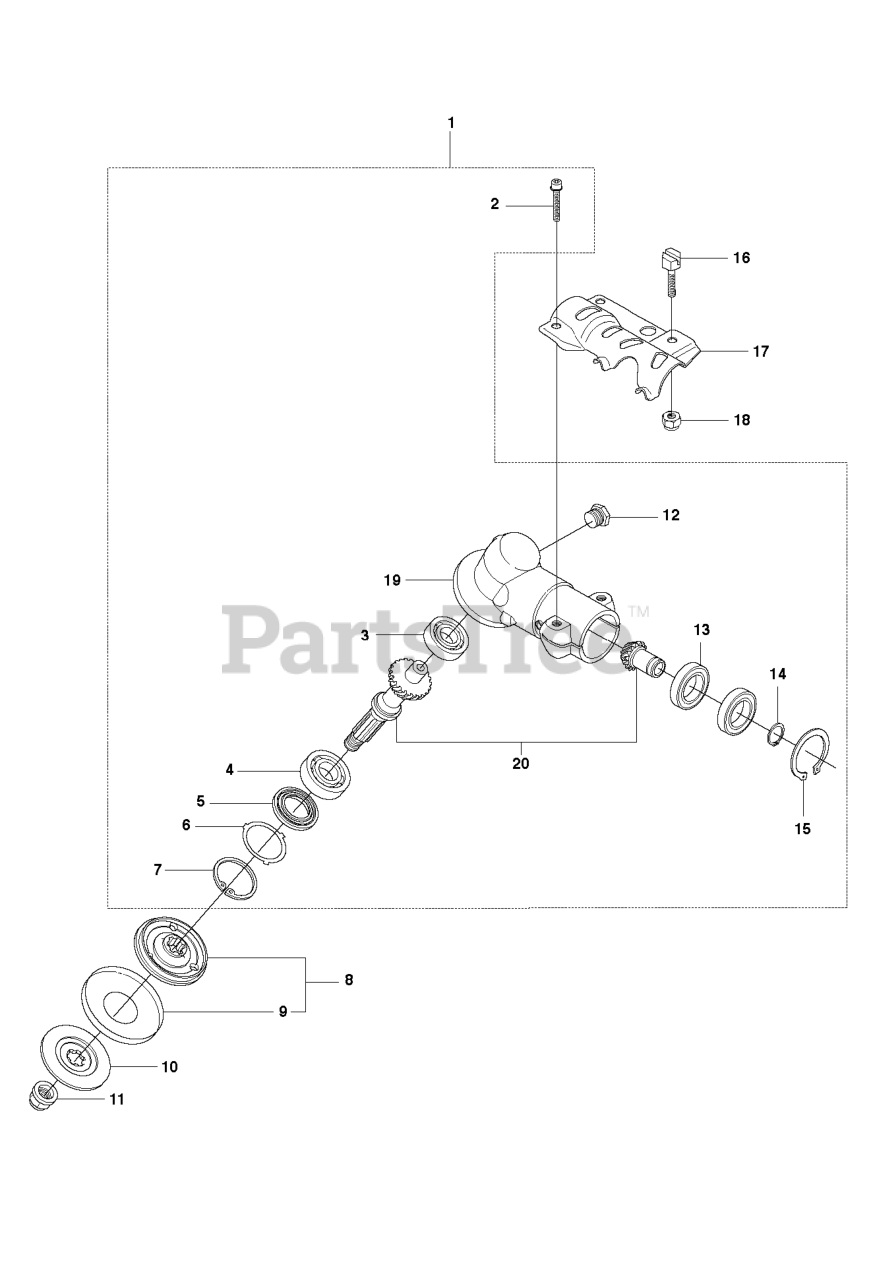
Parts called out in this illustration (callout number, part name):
1	GEAR ASSY
3	BALL BEARING
4	BALL BEARING
7	RETAINING RING SGH 35
8	RP CARRIER
9	RP TUBE INSERT
10	SUPPORT FLANGE
13	BALL BEARING
14	RETAINING RING SGA 15
15	RETAINING RING
17	BRACKET
18	LOCKNUT M6
19	GEAR HOUSING
20	SPARE PARTS KIT
